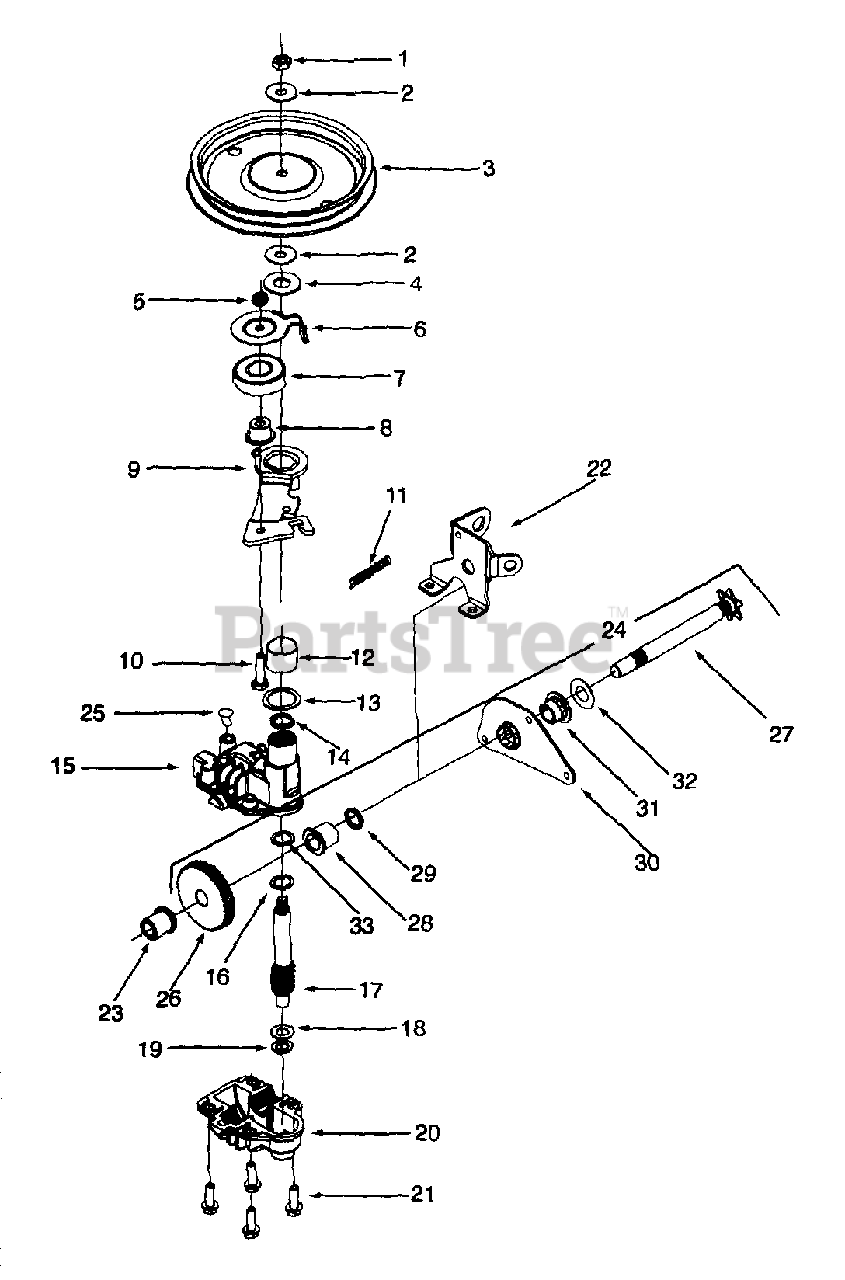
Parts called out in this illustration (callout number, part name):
1	Hx. Jam Nut 5/16-24
2	Bell Wash. .325 x .930 x .045
3	Pulley
4	Fl. Wash. .510 x 1.120 x .060
5	Hx. Jam Nut 1/4-28
6	Belt Keeper
7	Bearing
8	Flange Spacer
9	Idler Bracket Ass'y.
10	Hx. Cap Scr. 1/4-28 x 1.00 Gr. 5
11	Torsion Spring
12	Bearing Sleeve
13	Fl. Wash. .885 x 1.145 x .030
14	Oil Seal
15	Upper Housing Ass'y.
16	Fl. Wash. .504 x .700 x .030
17	Pinion Shaft 10T.
18	Thr. Wash. 3/8 x .70 x .030
19	Thr. Wash. .388 x .625 x .062
20	Lower Housing Ass'y.
21	Hx. Scr. 1/2-20 x .75
24	Shaft Ass'y.
26	Gear 34T.
27	Output Shaft 6T.
28	Flange Bearing
29	Oil Seal
30	Pivot Bracket
31	Flange Bearing
32	Wash. Fl. .508 I.D. x 1.00 O.D. x .020
33	Thrust Bearing
